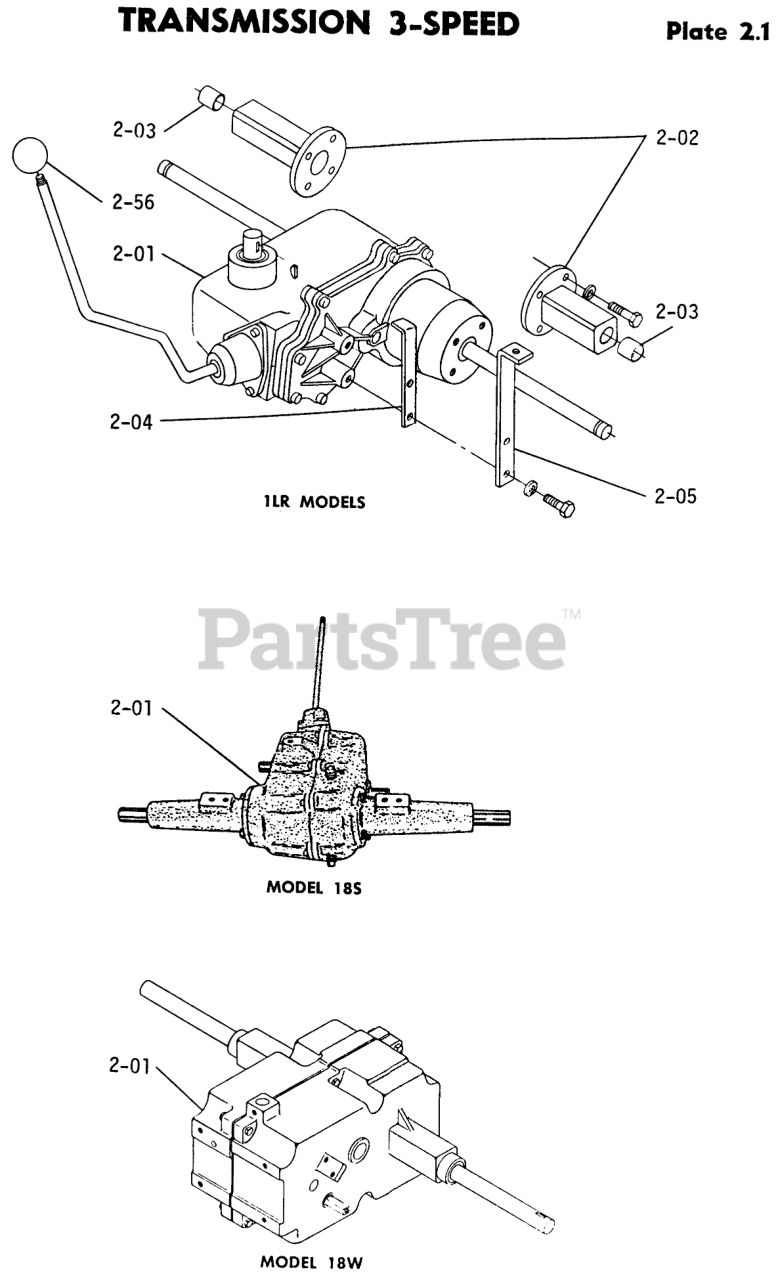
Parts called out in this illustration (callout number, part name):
2-01	Transmission Complete
2-01	Assy.-Transmission
2-01	Assy.-Transmission-Note 2
2-02	Bolt 5/16-18 x 1
2-02	Lockwasher
2-03	Bushing
2-04	Guide-Belt
2-05	Bolt 5/16-18 x 1
2-05	Lockwasher
